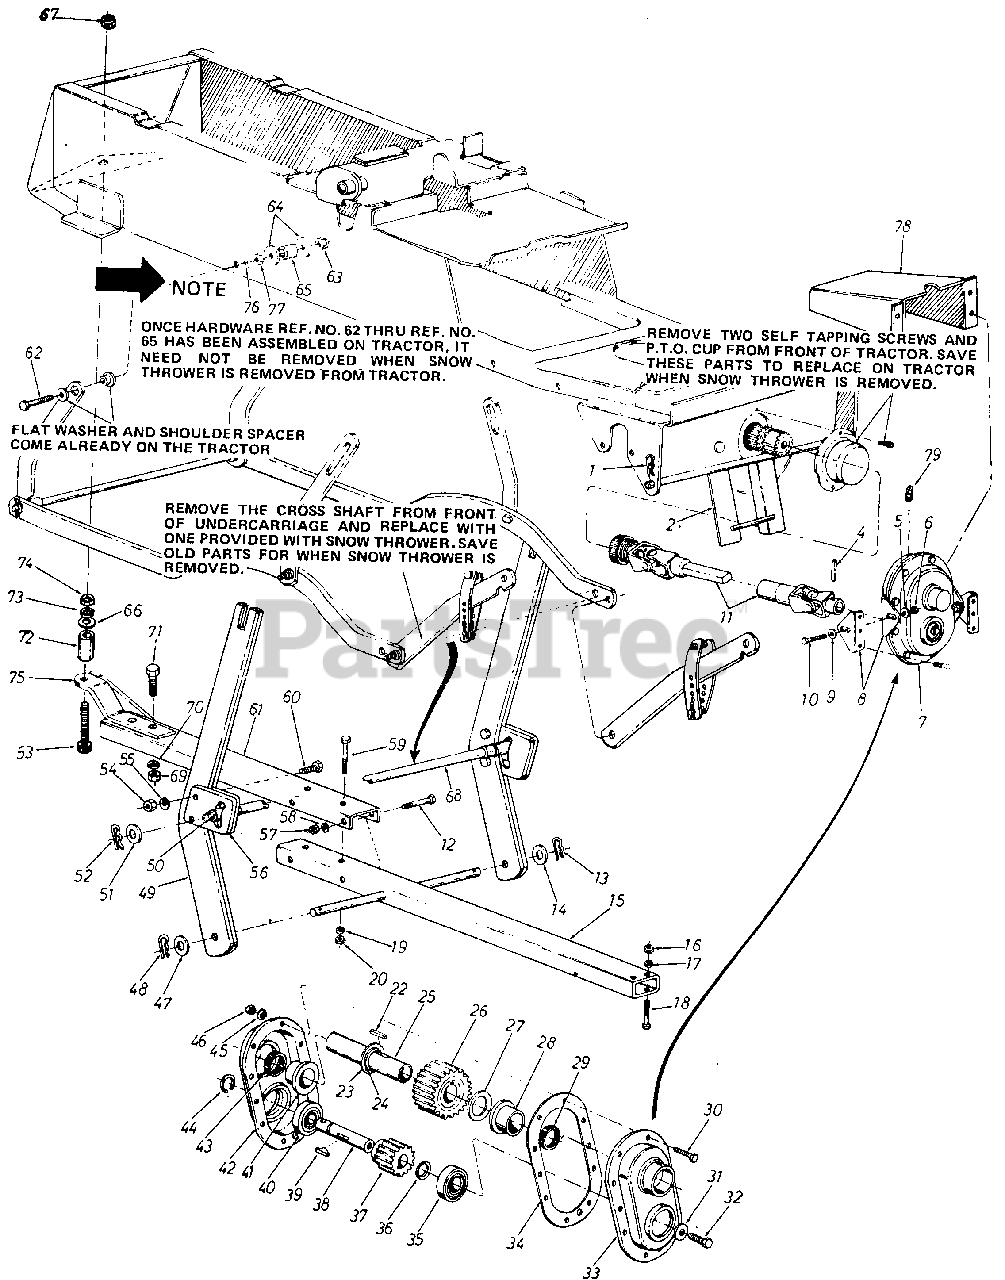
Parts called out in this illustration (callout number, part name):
1	Intern. Cotter Pin 3/4" Dia.
2	Guide Bracket Ass'y.
4	Spring Pin Spirol 1/4 " Dia. x Lg.
5	Belleville Wash. .341" I.D. x.88" O.D.
6	Hex Nut5/16-18 Thd.
7	Gear Box Ass'y. Comp.
8	Gear Box Support Brkt.
9	Belleville Wash. .341 " I.D. x .88" O.D.
10	Hex Sc 5/16-18 x .75" Lg.
11	Universal Drive Shaft Ass'y.
12	Hex Scr. 3/8-24 x 4.50" Lg.
13	Hair Pin Cotter
14	Fl.-Wash. .62" I.D. x 1.12" 0.D.
15	Lift Shaft Ass'y.
16	Hex Ins. Jam L.-Nut 3/8-24 Thd.
17	L.-Wash. 3/8" Scr.
18	Hex Scr. 3/8-24 x 2.75" Lg.
19	L.-Wash. 3/8" Scr.
20	Hex Ins. Jam L.-Nut 3/8-24 Thd.
22	Hi-Pro Key 1/4" x 7/8" Dia.
23	Fl.-Wash. 1.31" I.D. x 2.00" O.D. x .060
24	Snap Rinq for 1. 25" Dia. Shaft
25	Gear Shaft 1.25" Dia. x 6.0" Lg.
26	28 Teeth Spur Gear
27	Fl.-Wash. 1.31" I.D. x 2.00 O.D. x .060
28	Flange Bearing 1.25" I.D. x 1.75" O.D.
29	Oil Seal 1.25" I.D. x 1.75" O.D. x .26
30	Hex Scr. 1/4-28 x .88" Lg.
31	Fl.-Wash. .40 I.D. x 1.25" O.D. x . 1 60
32	Hex L.-Scr. 3/8-24 x 1.00" Lg.
33	Complete Gear Housing Half-L.H.
34	Gasket
35	Ball Bearing 1.00" I.D. x 2.00" 0. D.
36	Fl.-Wash. 1.03" I.D. x 1.63" x .090
37	15 Teeth Spur Gear
38	Input Shaft
39	Woodruff Key 1/4" x 3/4" Dia.
40	Ball Bearing 1.00" I.D. x 2.00" O.D.
41	Flange Bearing 1.25" I.D. x 1.75" O.D.
42	Complete Gear Housing Half-R.H.
43	Oil Seal 1.25" I.D. x 1.75 " O.D. x .26
44	Snap Ring for 1.00" Dia. Shaft
45	SpringWash. 1/4" I.D.
46	Hex Nut 1/4-28 Thd.
47	Fl.-Wash. .62" I.D. x 1.12" O.D.
48	Hair Pin Cotter
51	Fl.-Wash. .62" I.D. x 1.12" 0.D.
52	Hair Pin Cotter
53	Hex Bolt 5/8-18 x 4.00" Lg.
54	Hex Nut 5/16-18 Thd.
55	L.-Wash. 5/16" Scr.
58	L.-Wash. 3/8" Scr.
59	Hex Scr. 3/8-24 x 2.75"
60	Hex Scr. 5/16-18 x 1.00" Lg.
61	Lift Bracket
62	Hex Scr. 3/8-24 x 2.50"
63	Hex Jam L.-Nut 3/8-24 Thd.
64	Fl.-Wash. .375 I.D. x 1.00" O.D. x .1.35"
65	Spacer .275 I.D. x .625 O.D. x .440
66	Fl.-Wash. .66" I.D. x 1.25" O.D. x . 100
67	Hex Jam L.-Nut 5/8-18 Thd.
68	Cross Shaft Ass'y.
69	Hex Nut 1/2-13 Thd.
70	L.-Wash. 1/2" Scr.
71	Hex Scr. 1/2-13 x 1.25"
72	Bushing
73	L.-Wash. 5/8" Scr.
74	Hex Jam Nut 5/8-18 Thd.
77	Hex Nut 3/8-24Thd.
78	Drive Shaft Cover
79	Grease Fitting
